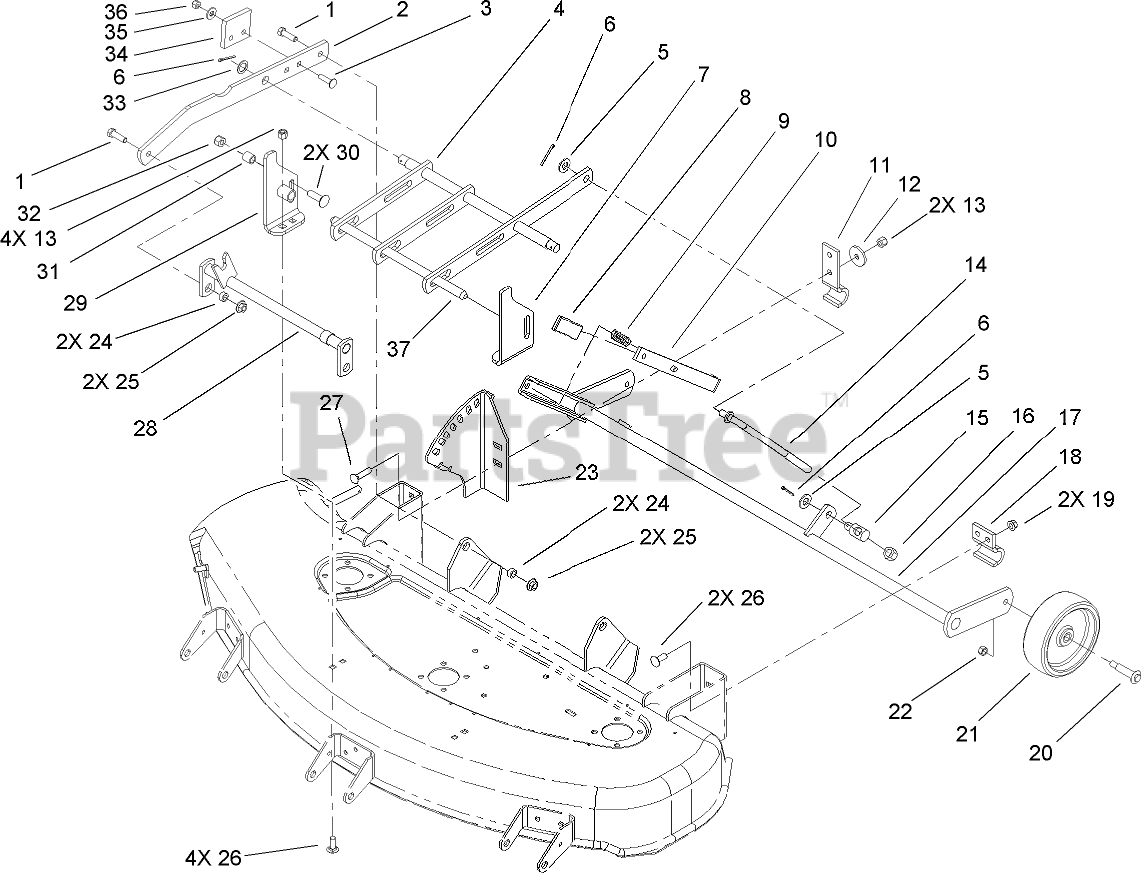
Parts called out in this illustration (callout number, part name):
1	SCREW-HH
2	BAR-DRAFT
3	SCREW-CARR
4	BAR-LEVELER
5	WASHER-FLAT
6	PIN-COTTER
7	BRACKET-FRONT DECK, LH
9	SPRING-COMPRESSION
10	LEVER-HOC
11	BRACKET-PIVOT
12	WASHER-SUPPORT
13	NUT-LOCK, NI
14	ROD-ADJUSTMENT
15	TRUNNION
16	NUT-LOCK, NI
17	WHEEL SUPPORT ASM
19	NUT-FLANGE
20	BOLT-SHOULDER
21	WHEEL
22	NUT-HEX
23	QUADRANT ASM
24	SPACER
25	LOCKNUT-FLANGE
26	BOLT-CARR
27	SCREW-CARR
28	HITCH ASM
29	BRACKET-FRONT DECK, RH
30	BOLT-CARR
31	SPACER
32	NUT-LOCK, NI
33	WASHER-FLAT
34	BUMPER
35	WASHER-FLAT
36	NUT-LOCK, NI
37	Shaft-Front
